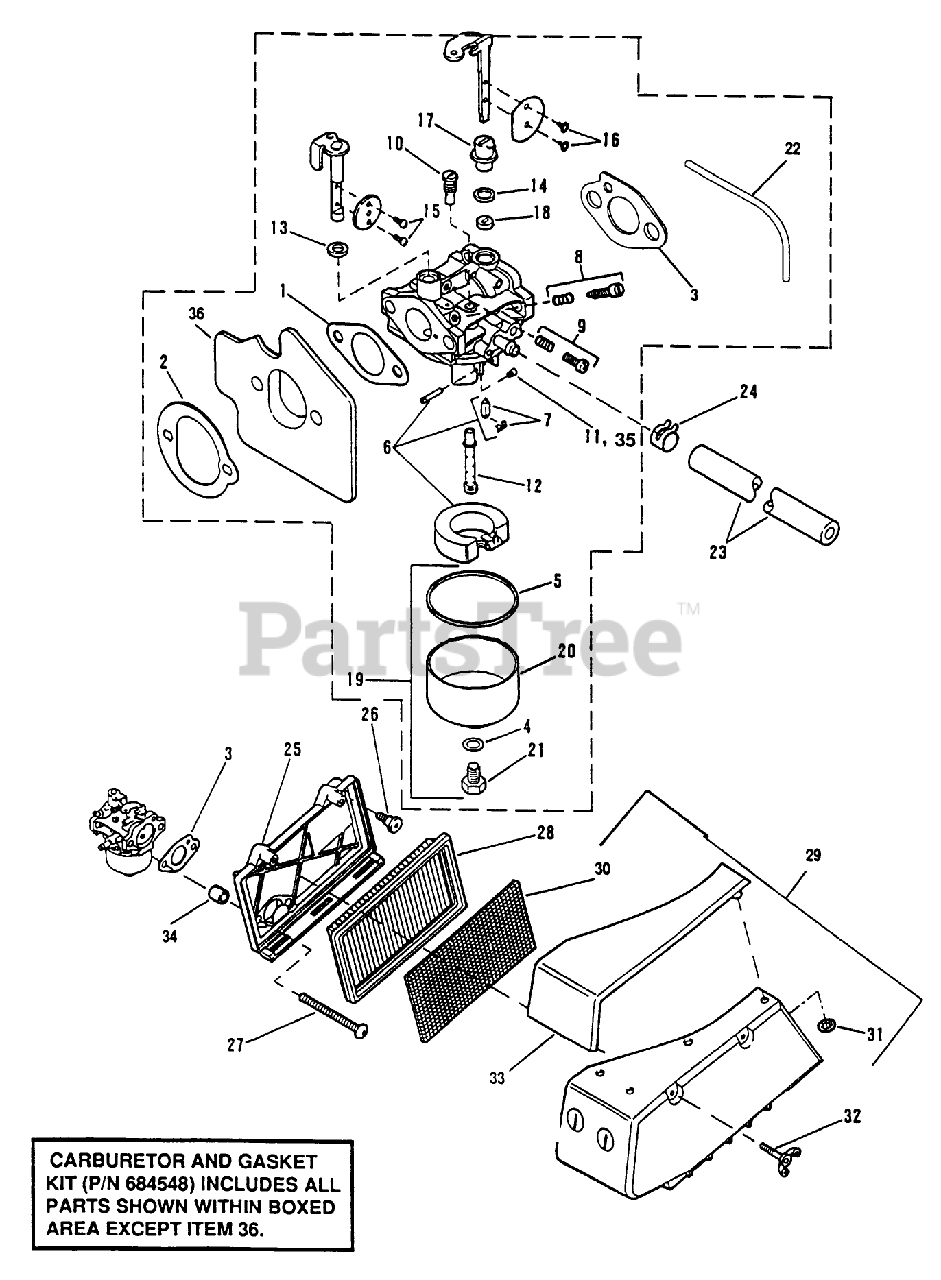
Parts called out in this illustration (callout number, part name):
1	GASKET SM
2	GASKET SM
3	GASKET-FIL SM
4	GASKET-BOWL RET S
5	GASKET-FUELBOWL S
7	NEEDLE & CLIP S
10	PILOT JET
11	CARB JET
14	SEAL CHOKE SHAFT
16	SCREW CHOKE VALVE
21	SCREW,BOWL RET S
22	HOSE-CARB.VENT SM
24	HOSE CLAMP SM
28	ELEMENT-AIR SM
29	AIR FILTER COVER
31	NUT-PUSH
33	COVER-AIR BOX
35	MAIN JET
